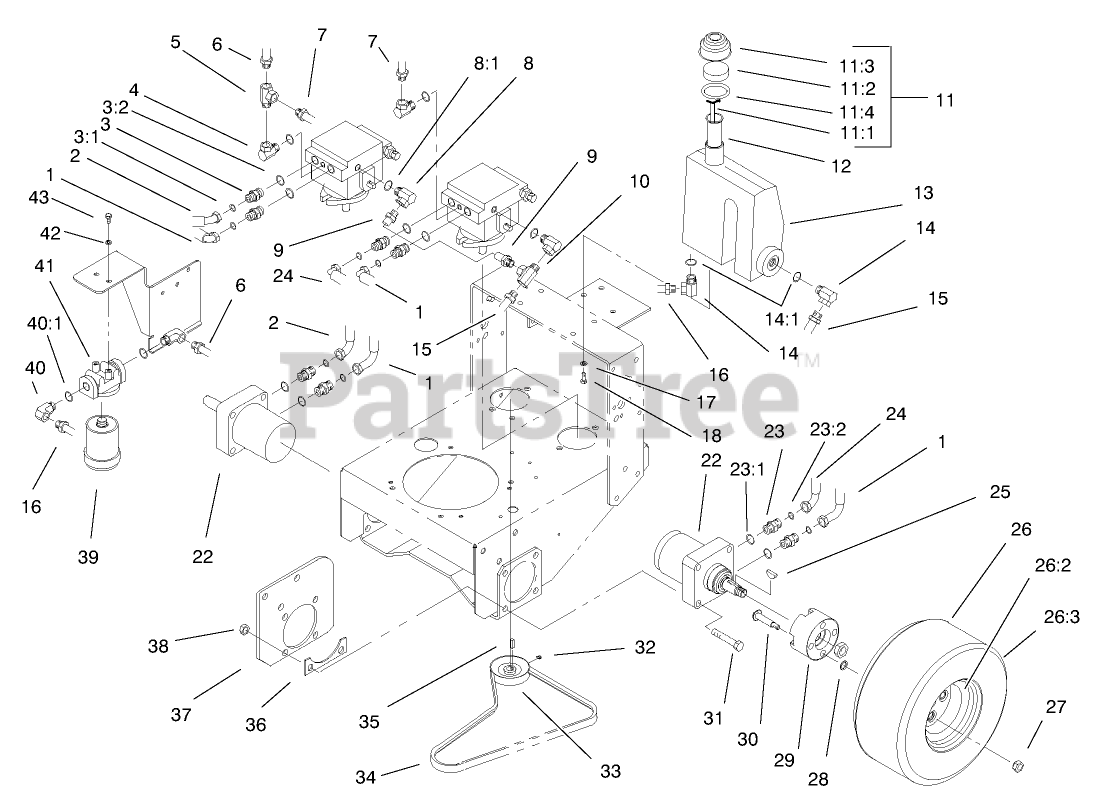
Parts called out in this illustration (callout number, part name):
1	HYDRAULIC HOSE ASM
2	HYDRAULIC HOSE ASM
3	FITTING-STRAIGHT
3:1	O-RING
3:2	O-RING
4	SWIVEL-PIPE, FEMALE
5	FITTING-HYD, TEE
6	HYD HOSE ASM
7	HYD HOSE ASM
8	FITTING-HYD, 90 DEG
8:1	O-RING
9	HYD HOSE ASM
10	FITTING-HYD, TEE
11	OIL CAP ASM
11:1	DIPSTICK
11:2	FOAM-FILTER, OIL CAP
11:3	CAP-OIL
11:4	O-RING
12	SCREEN-FILLER
13	RESERVOIR-OIL
14	FITTING-HYD, 90 DEG
14:1	O-RING
15	HYD HOSE ASM
16	HYD HOSE ASM
17	WASHER-LOCK
18	SCREW-HH
22	WHEEL MOTOR ASM
23	FITTING-STRAIGHT
23:1	O-RING
23:2	O-RING
24	HYDRAULIC HOSE ASM
25	KEY-WOODRUFF
26	WHEEL AND TIRE ASM
26:2	WHEEL
27	NUT-LUG
28	PUSHNUT
29	HUB-WHEEL
30	SCREW-HH
31	SCREW-HH
32	SCREW-SET
33	PULLEY-PUMP
34	BELT-V
35	KEY-PUMP
36	SPACER-FRAME
37	PLATE-FRAME
38	NUT-LOCK, NI
39	CARTRIDGE-FILTER, OIL
40	FITTING-HYD, 90 DEG
40:1	O-RING
41	HEAD-FILTER
42	WASHER-LOCK
43	SCREW-HH
